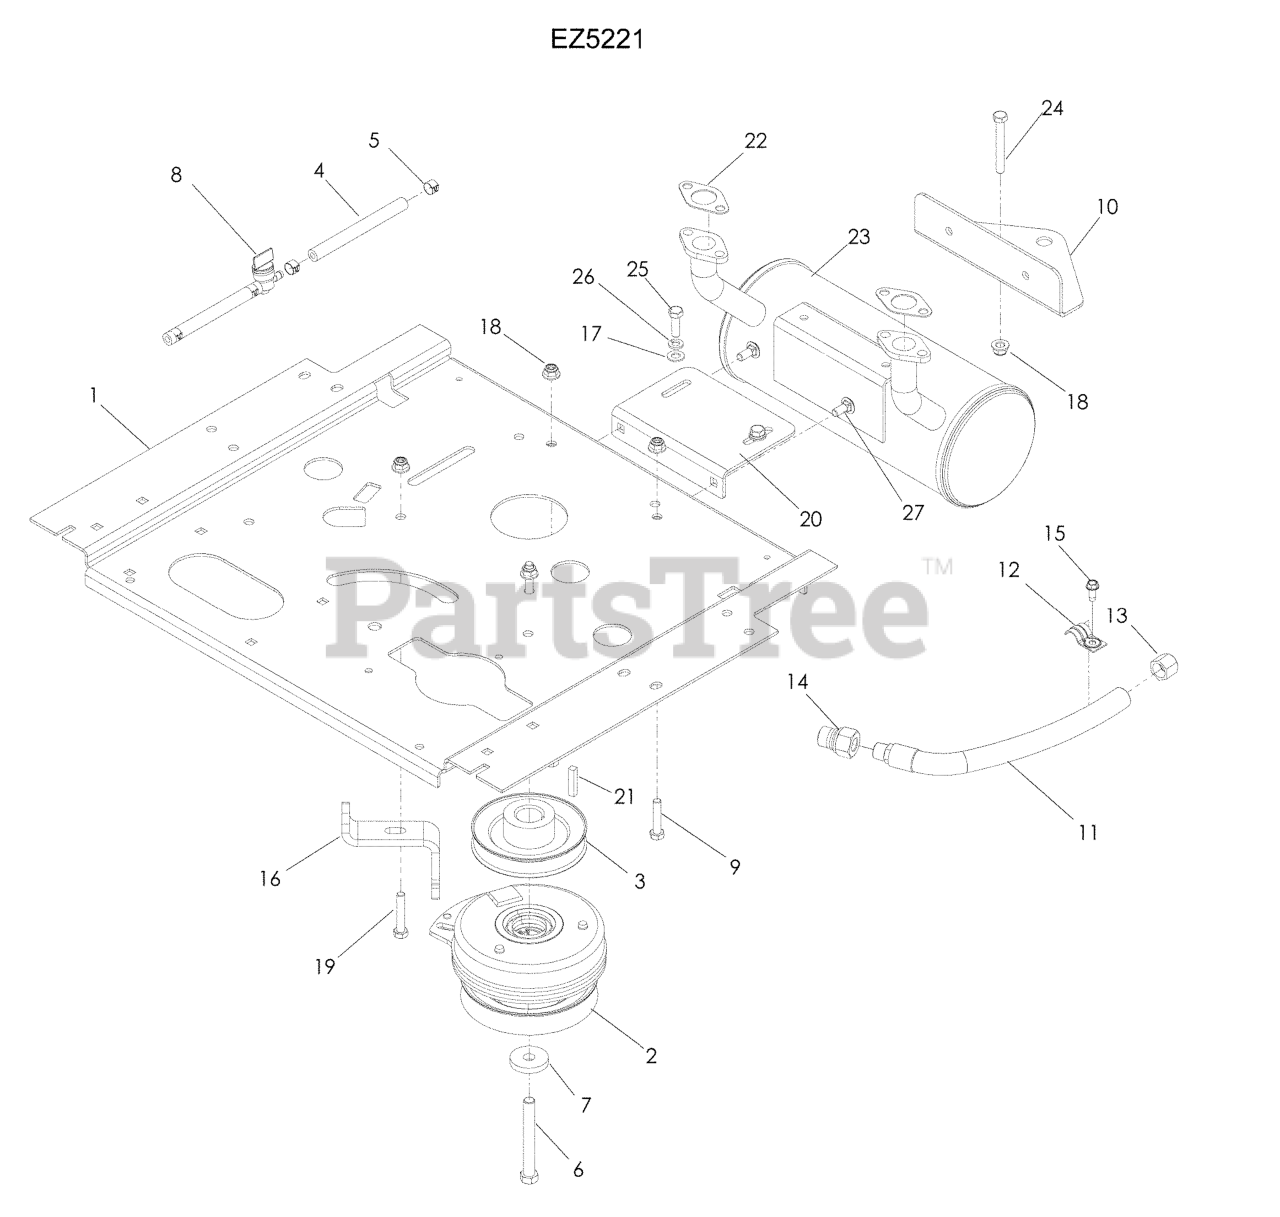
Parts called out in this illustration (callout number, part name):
1	PLATE, ENGINE, BLACK
2	CLUTCH, 105 FT-LBS
4	FUEL LINE 5"
5	HOSE CLAMP
6	HCS 7/16-20X3-1/2 GR 5 ZN
7	CLUTCH, WASHER
8	FUEL VALVE
9	CAPSCREW 5/16 X 1/1/2 HEX HEAD
10	HITCH, BLACK
11	OIL DRAIN HOSE
14	ADAPTER, OIL DRAIN
15	SCREW 1/4 X 5/8
16	STOP, CLUTCH BLK
17	FLAT WASHER 5/16 SAE
18	5/16-18 NYLOC FLANGE NUT
19	HCS 5/16C X 1 3/4
20	BRACKET MUFFLER, BLK
21	KEY, 1/4 SQ X 1 1/4
22	EXHAUST GASKET - KAW
23	MUFFLER KAWASAKI GEN II
24	BOLT 5/16C X 2 1/2
25	HCS 5/16C X 1
26	WASHER.LOCK.HVY.HLCL.SPR.5/16
27	BOLT 5/16C X 3/4" CARRIAGE
